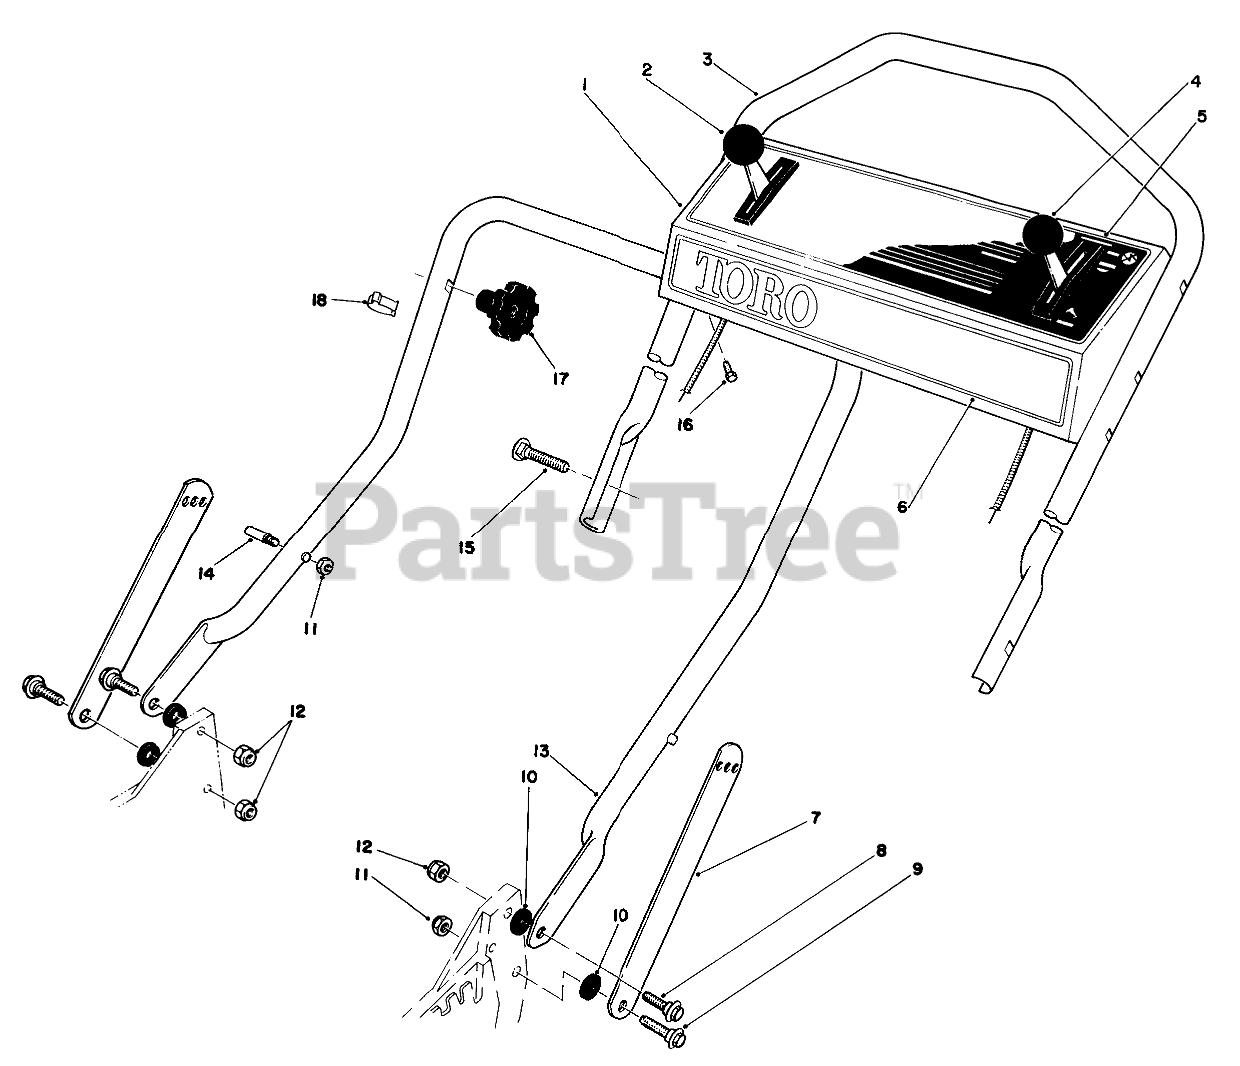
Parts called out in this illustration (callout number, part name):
1	Panel & Control (Incl. Ref. #5)
2	GROUND SPEED CONTROL
3	Handle-Upper
4	SERVICE THROTTLE CONTRO
5	Decal-Instruction Panel
6	Decal-Toro
7	Handle Latch
8	SCREW-SHOULDER
9	SCREW-SHOULDER
10	SPACER
11	NUT-LOCK, NI
12	NUT-LOCK, NI
13	Handle-Lower
14	HANDLE PIN
15	5/16-18 X 2 HNDLE SCREW
16	SCREW-HWHTF
18	BOWDEN CLIP
